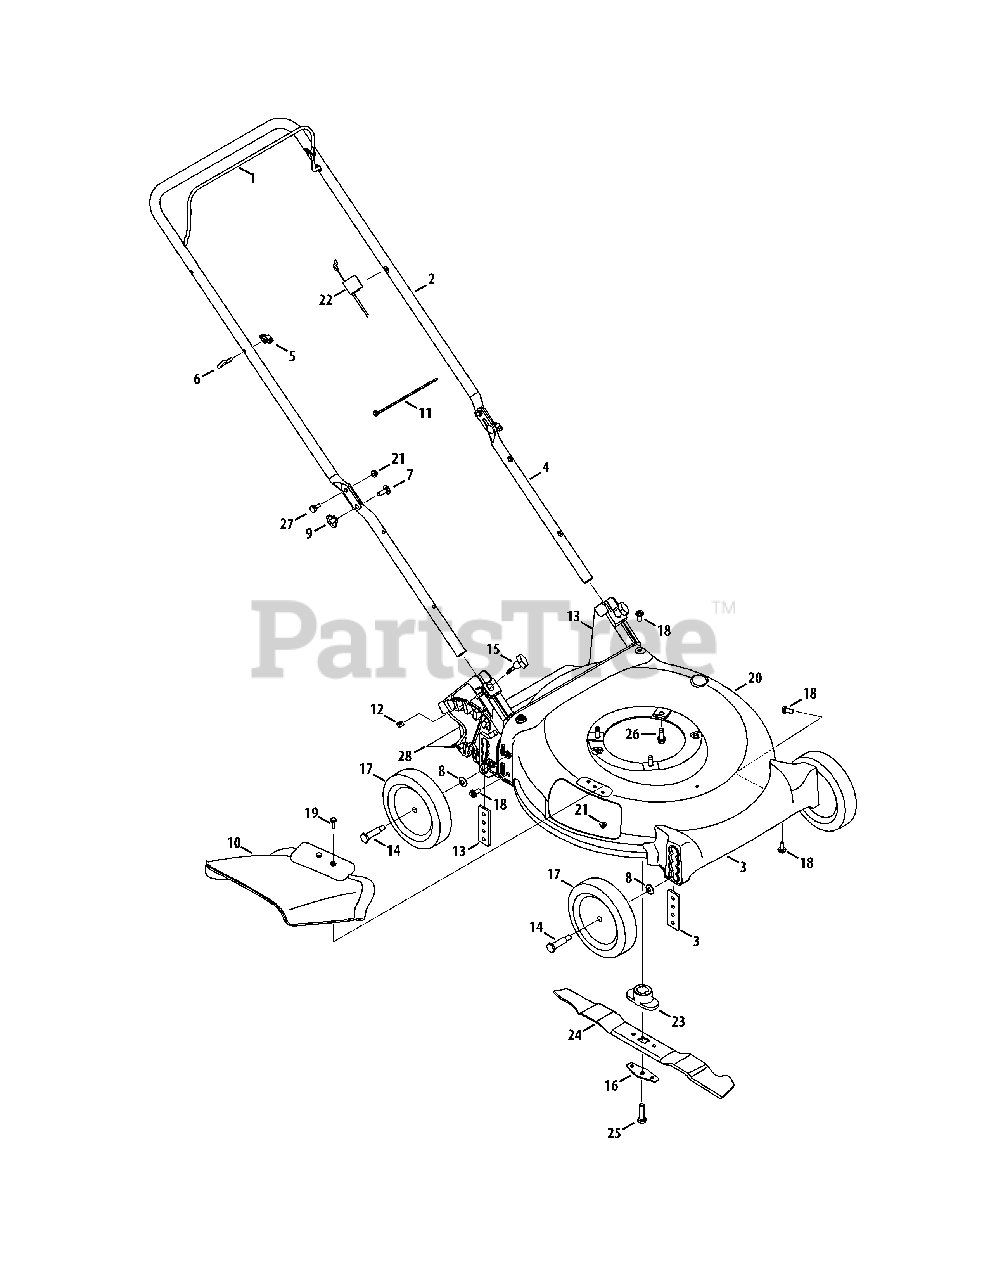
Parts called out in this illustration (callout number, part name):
1	Blade Control
2	Upper Handle
3	Front Cover Assembly
4	Lower Handle
5	Wing Nut
6	Rope Guide
7	Carriage Screw ,5/16-18
8	Washer, .401 x .870 x .060
9	Wing Knob
10	Side Chute
11	Cable Tie
12	Nut, Sq., 1/4-20
13	Rear Baffle, Generic
13	Rear Baffle, Home Depot
13	Rear Baffle, Lowes
14	Shoulder Screw
15	Wing Nut
16	Blade Bell Support
17	Wheel, 7" Star-Dia., Oys. Gray
18	Screw, 5/16-14 x .750
19	Screw, 1/4-20 x .750
20	Deck , 21" - Red
20	Deck , 21" - Green
21	Nut, Flange Lock, 1/4-20
22	Control Cable
23	Blade Adapter
24	Mulching Blade
25	Screw , 3/8-24 x 1.50
26	TT Sems Screw, 3/8-16 x 1.0
27	Sldr. Screw, .375 x .126 x 1/4-20
28	Trail shield
